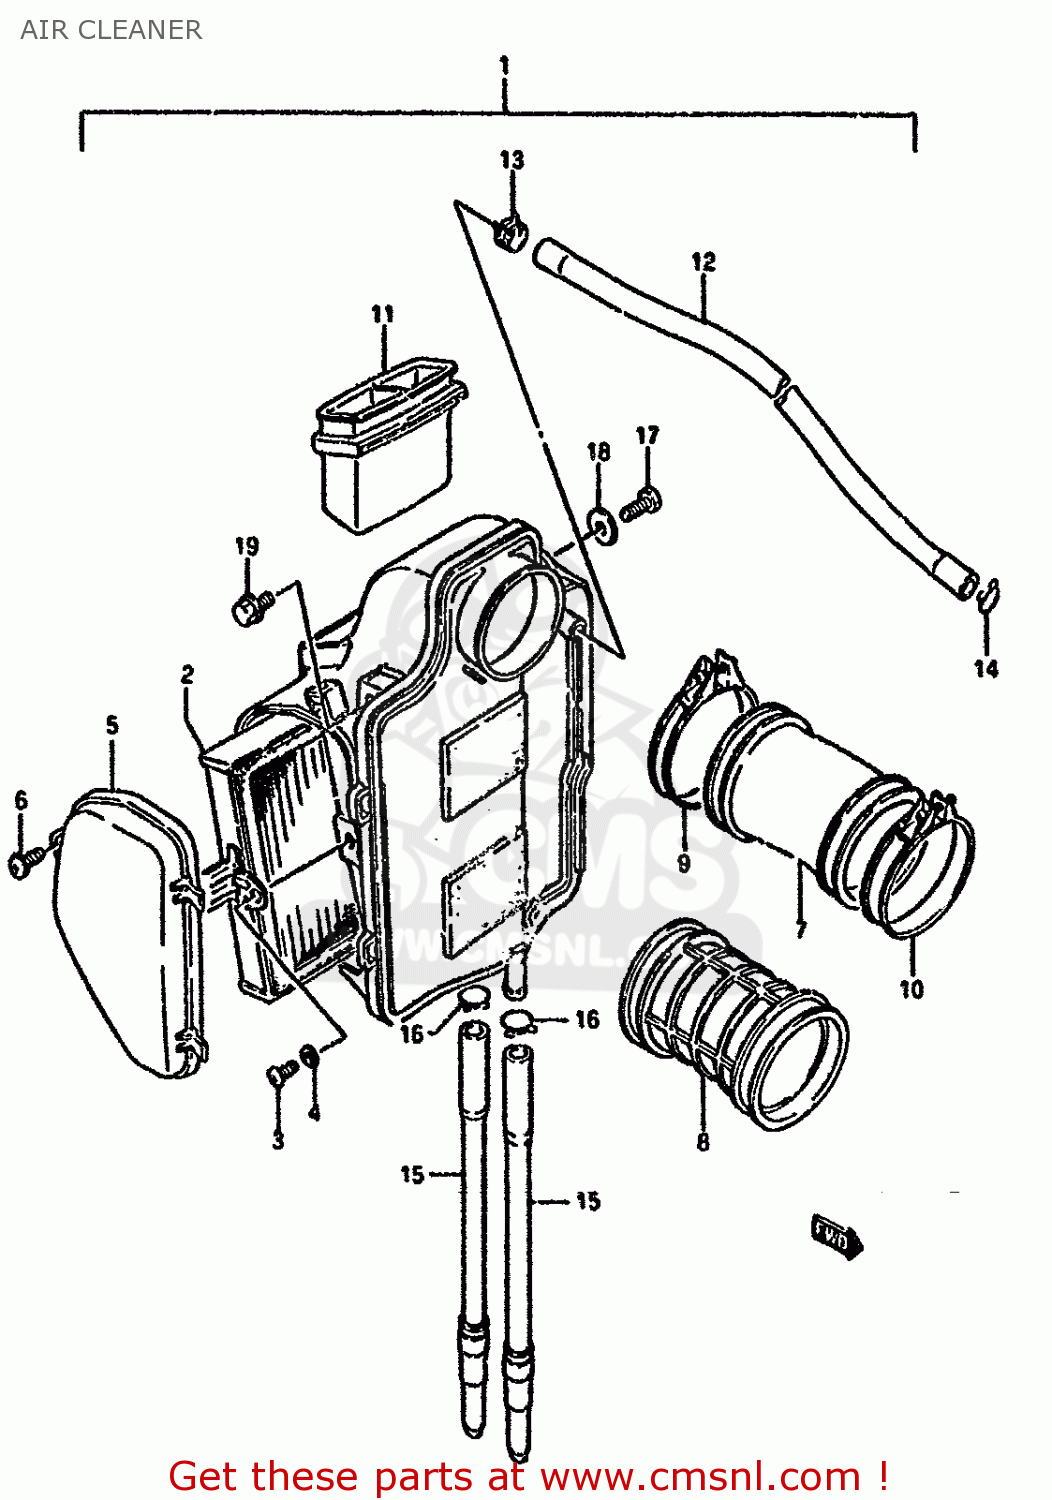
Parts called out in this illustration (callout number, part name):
1	CLEANER ASSY,AIR
2	FILTER ASSY,AIR
3	SCREW
4	LOCK WASHER
5	CAP,AIR CLEANER
6	SCREW, FRONT & REAR
7	TUBE,AIR CLEANER OUTLET
8	TUBE,AIR CLEANER OUTLET
9	CLAMP
10	CLAMP
11	TUBE,INLET
12	TUBE,BREATHER
13	CLIP
14	CLIP
15	DRAIN TUBE
16	CLIP
17	BOLT
18	WASHER
19	BOLT
